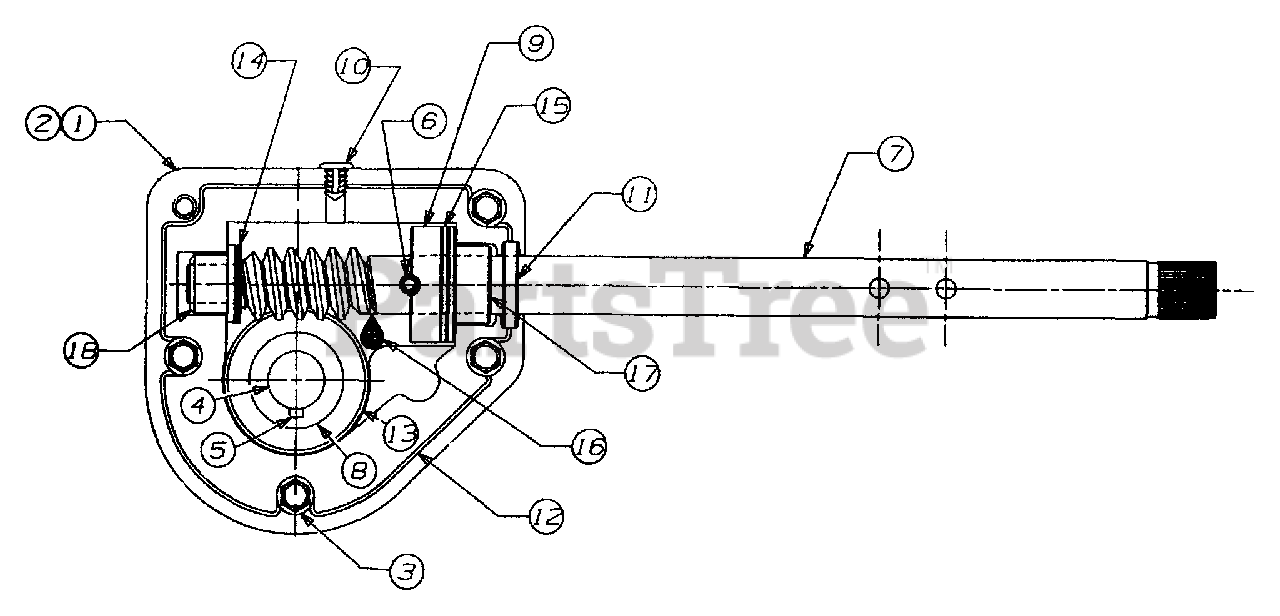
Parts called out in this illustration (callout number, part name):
1	Housing - R.H.
2	Housing - L.H.
3	Screw
4	Spiral Axle
5	Key, Hi-Pro
6	Spiral Pin
7	Shaft Worm
8	Worm Gear
9	Thrust Collar
11	Seal, Oil
12	Loctite 5699, Ultra
13	Washer
14	Washer
15	Washer
16	Grease
17	Flange Bearing
18	Flange Bearing
